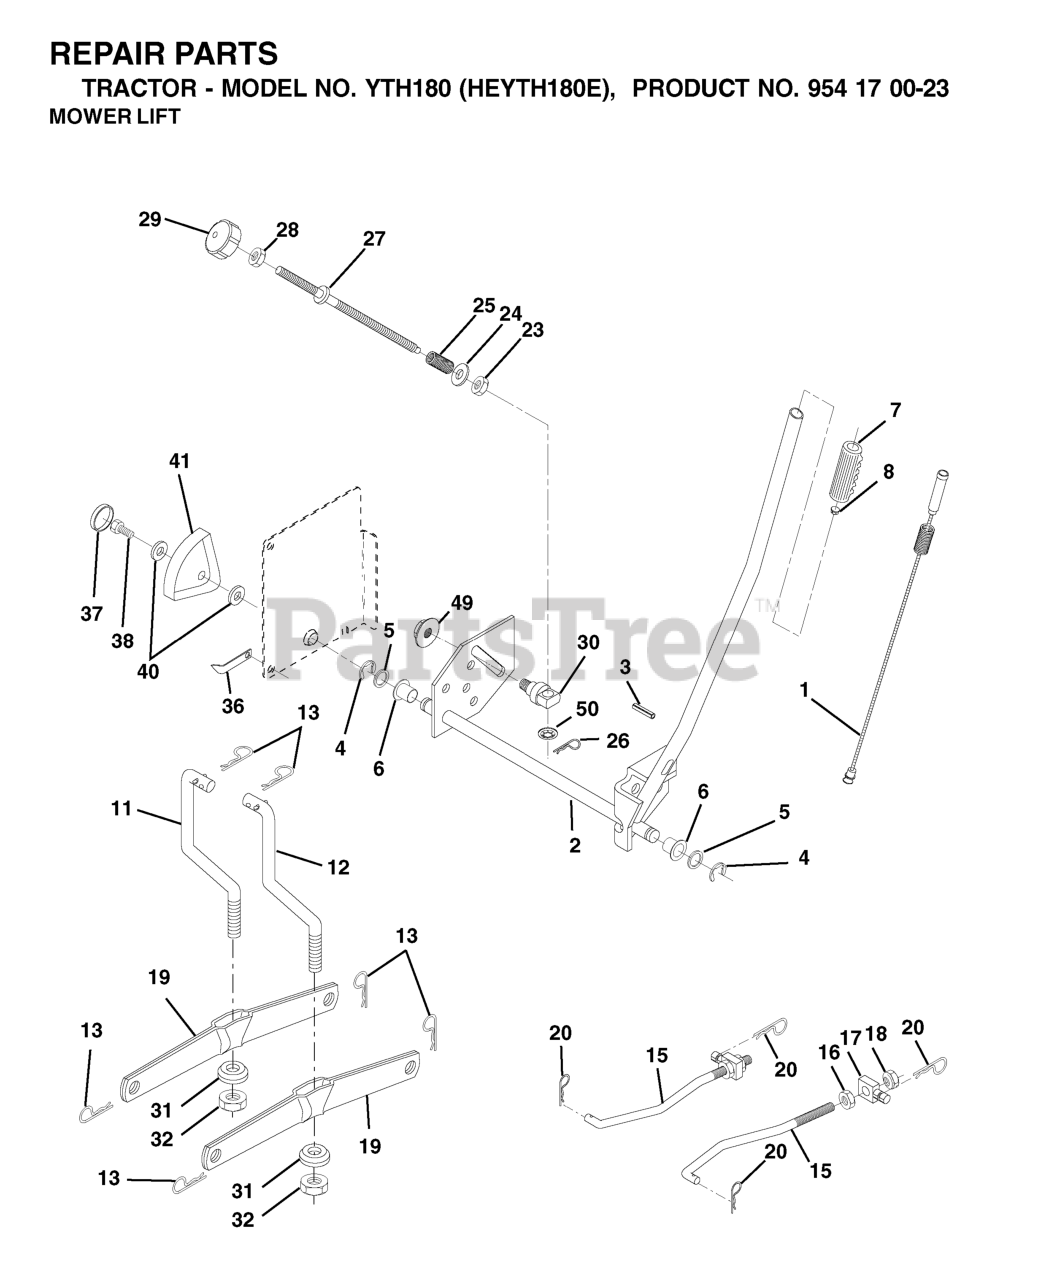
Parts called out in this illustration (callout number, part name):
1	WIRE ASM INNER W/ PLUNGER LT
2	SHAFT ASM R HANDLE
3	PIN GROOVE.
4	RETAINING RING LT
6	BEARING.NYLON
7	GRIP HANDLE
8	PLUNGER BUT KIT
11	LINK LIFT LH
12	LINK LIFT RH
13	RETAINER-SPRNG RB
15	LINK.SUSPENSION.FRONT
16	NUT.HEX.JAM.1/2-13
17	TRUNION
18	NUT.LK.W/WSH.1/2.
19	ARM.REAR.SUSPENSION
20	SPRING RETAINER
25	SPRING**
26	RETAINER CLIP
27	ROD ADJ LIFT
28	NUT
29	KNOB INF 3/8-16
31	BEARING.PIVOT.LIFT
32	NUT CROWNLOCK 3/8-24
36	POINTER, HEIGHT INDICATOR(2 2)
38	SCREW 5/16-18X1
41	IND. HEIGHT STLT
49	NUT
50	NUT PUSH M
